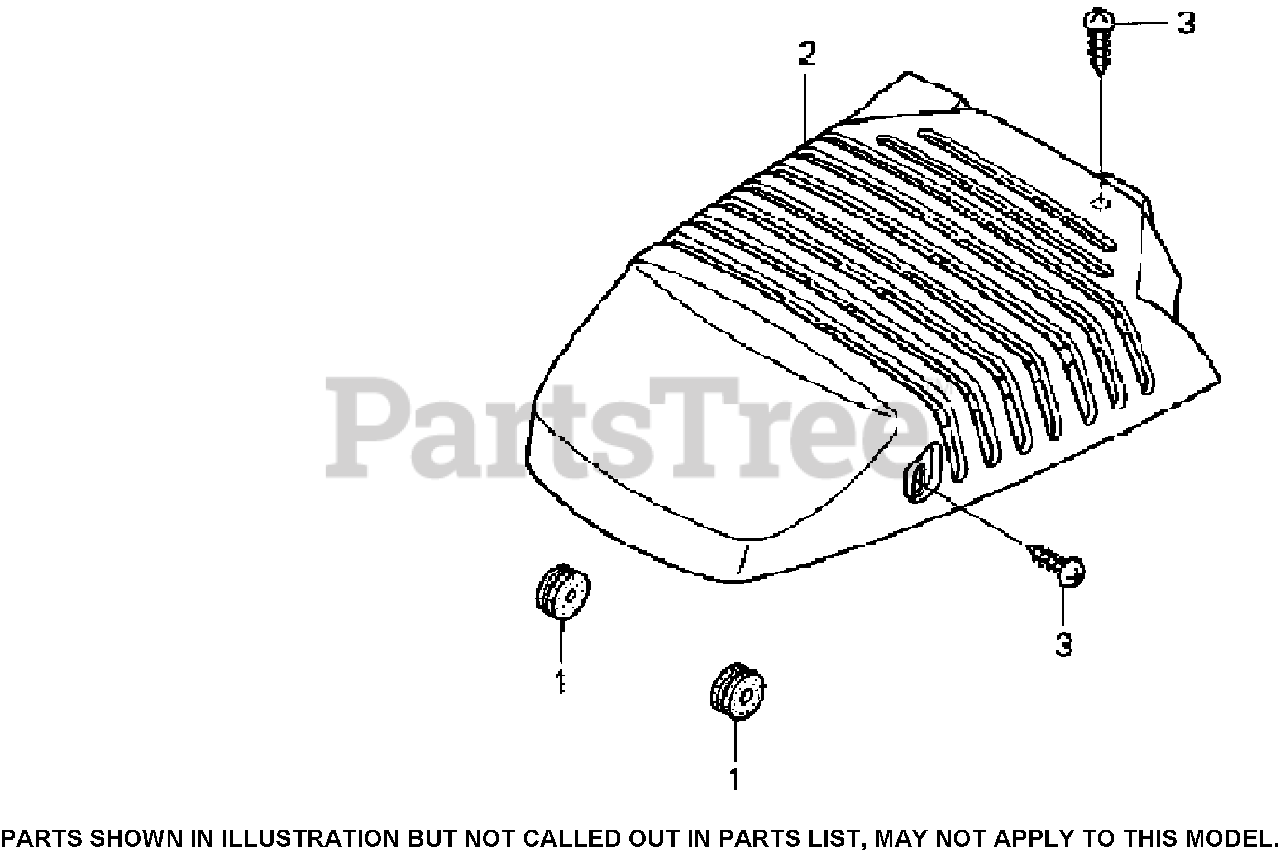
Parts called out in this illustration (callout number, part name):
1	GROMMET-ROD, CHOKE
2	COVER-TOP
3	SCREW-TAPPING (4X16)
